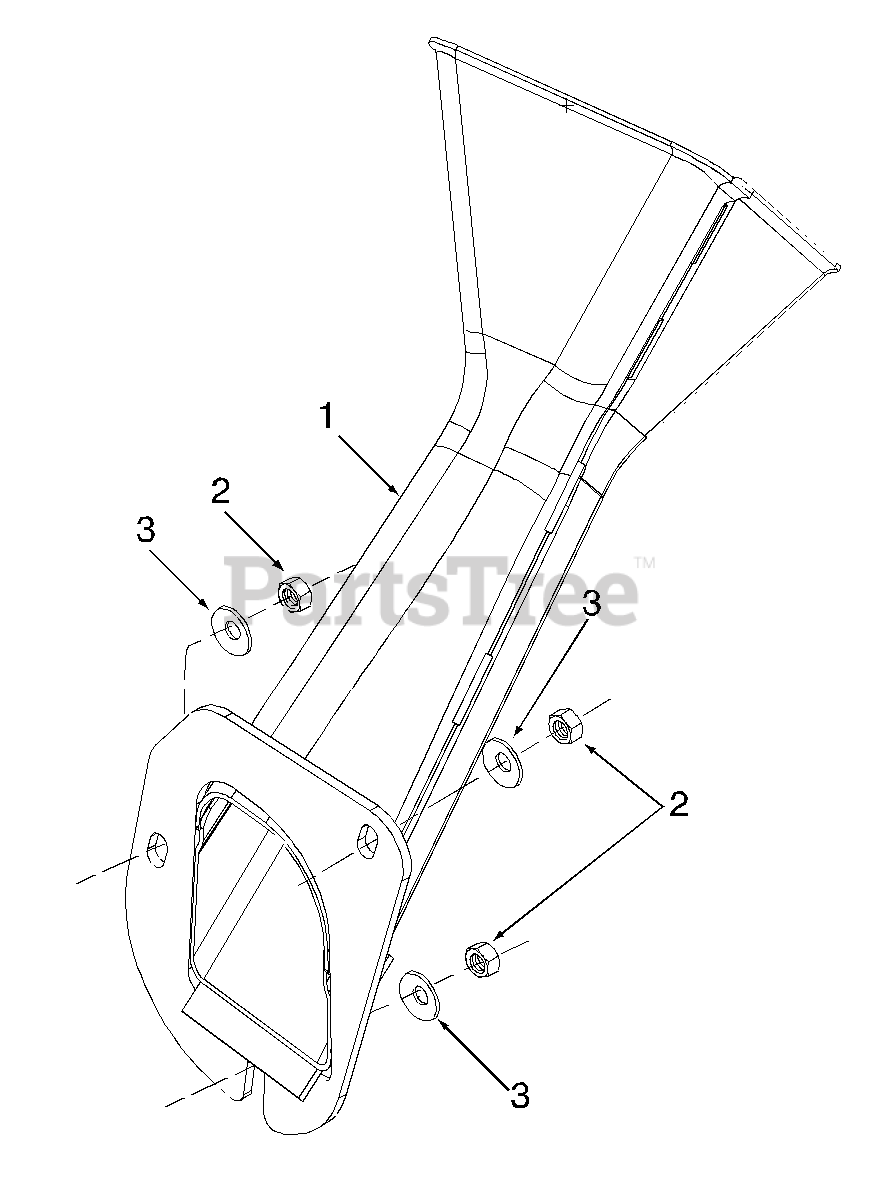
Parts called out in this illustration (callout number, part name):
1	Chute Assembly, Chipper
2	Nut, Hex, 5/16-18
3	Washer, Bell, .345
